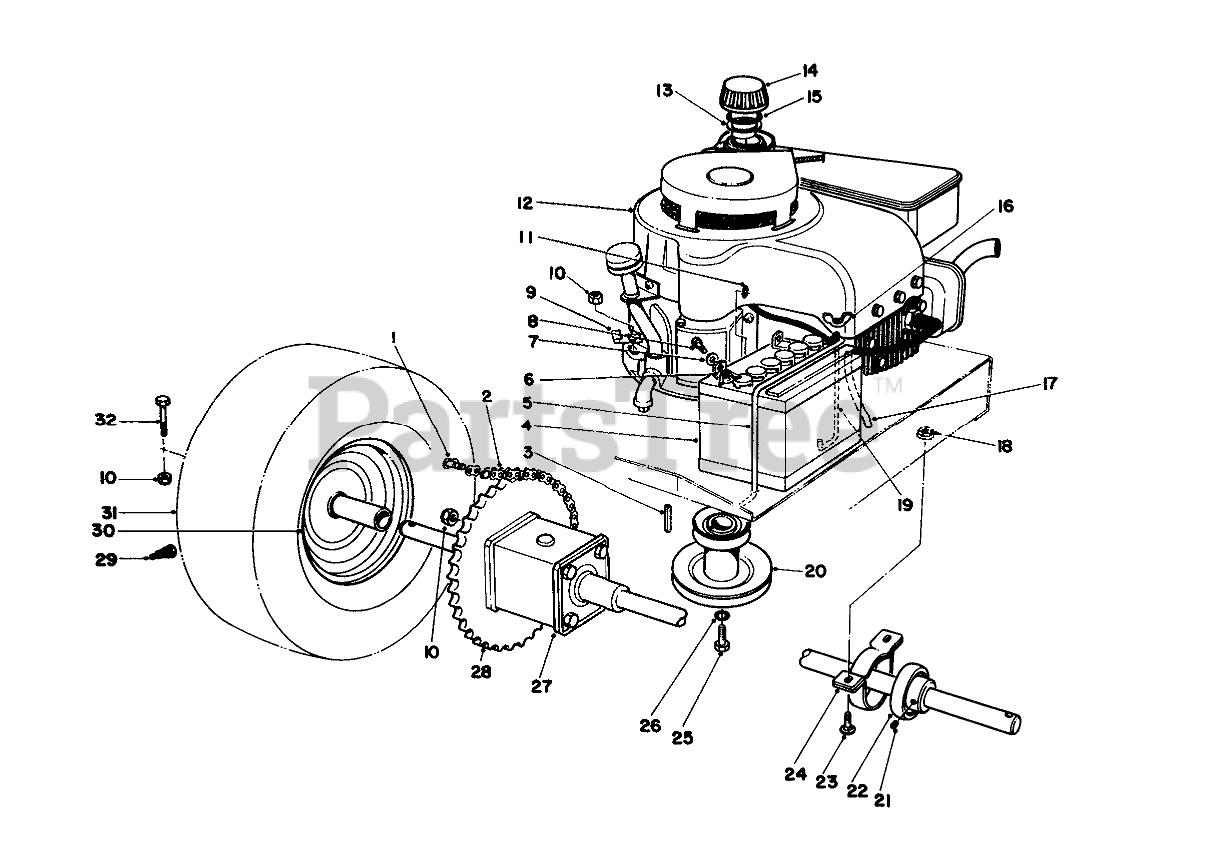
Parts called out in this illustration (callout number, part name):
1	LINK-CONNECTING
2	Chain-Roller (Incl. Ref. #1)
4	Battery
5	BATTERY HOLDOWN
6	NUT-WING
7	WASHER-FLAT
8	SCREW-HH
9	CLAMP
10	NUT-LOCK, NI
11	WASHER-LOCK/EXT
13	GAS CAP BAFFLE
14	Gas Cap Assembly (Incl. Ref. #13, 15)
15	GASKET
16	NUT-WING SPECL
17	TUBE-BATT DRAIN/80-2600
18	NUT-HF
19	POST-BATTERY
20	ENGINE PULLEY BO
21	SCREW-HSH
22	Bearing (Incl. Ref. #20)
23	SCREW-CARR
24	RTNR-PILLOW BLK
25	SCREW-HH
26	WASHER-LOCK
27	DIFFERENTIAL
28	45 T SPROCKET
29	STEM-VALVE
30	WHEEL-REAR
31	Tire
32	Bolt
